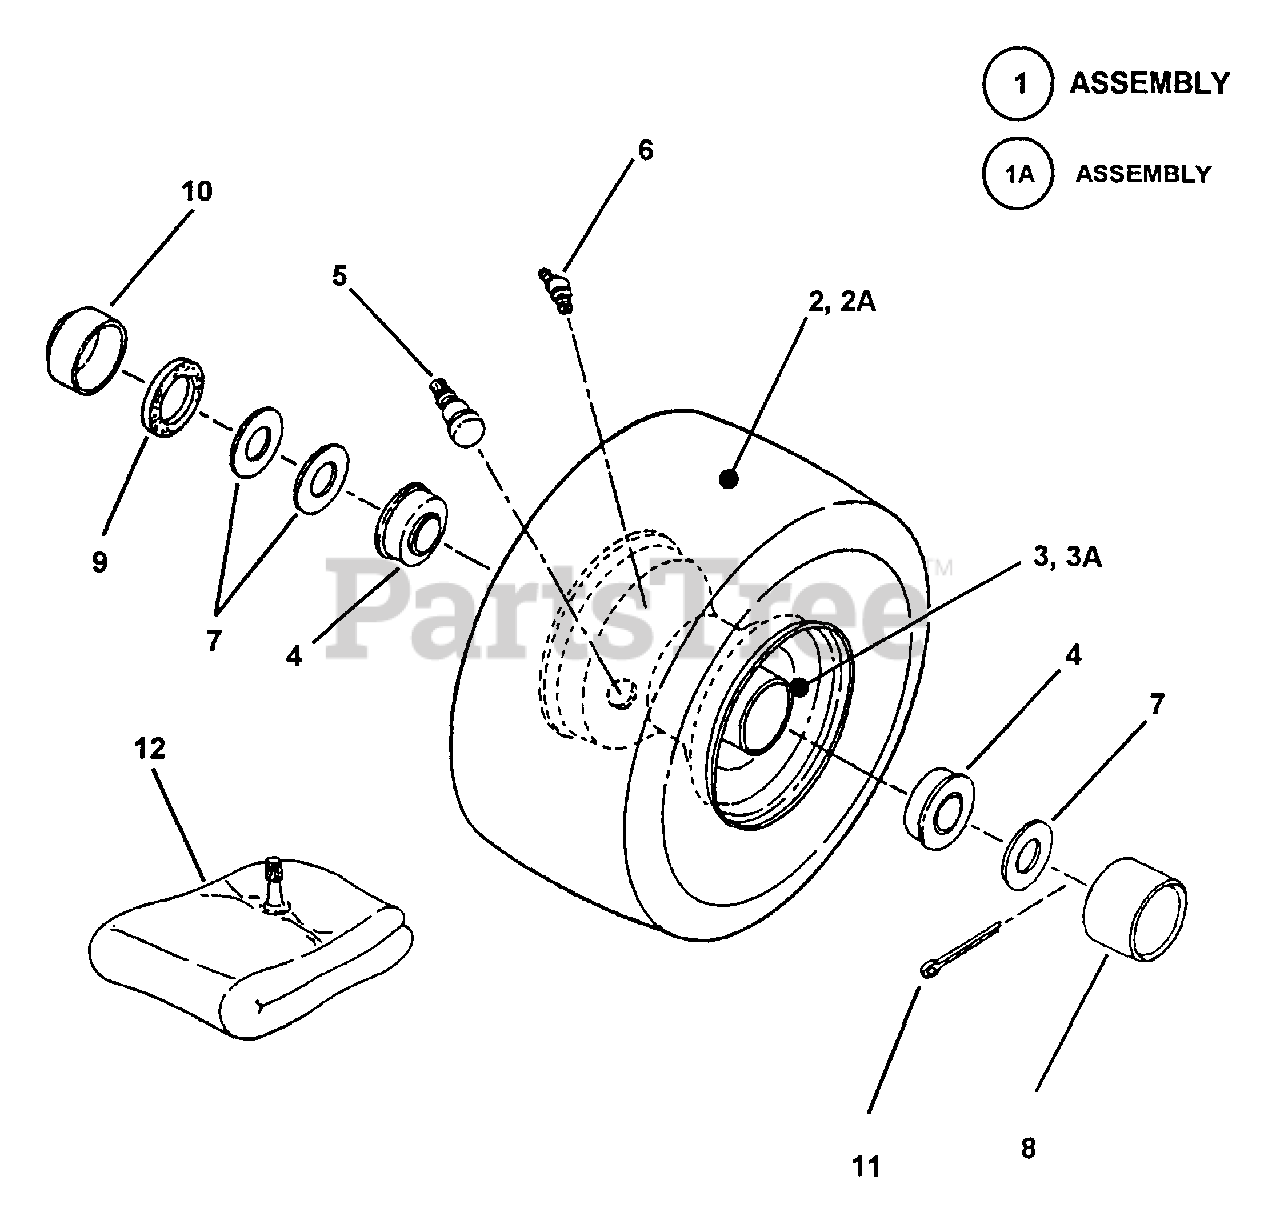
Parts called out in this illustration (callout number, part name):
1	ASSEMBLY, Front Tire & Rim
1A	ASSEMBLY, Front Tire & Rim
2	TIRE, Pneumatic 4.10/3.50 x 4
2A	TIRE, Pneumatic 11 x 4.00-4, Carlisle
3	RIM
3A	RIM
4	BEARING, Ball
5	VALVE, Air (Snap-in)
6	FITTING Lube
7	WASHER
8	CAP, Hub
9	SEAL, Felt
10	CAP, Dust
11	PIN, 5/32 x 1" Cotter
12	TUBE, Inner
